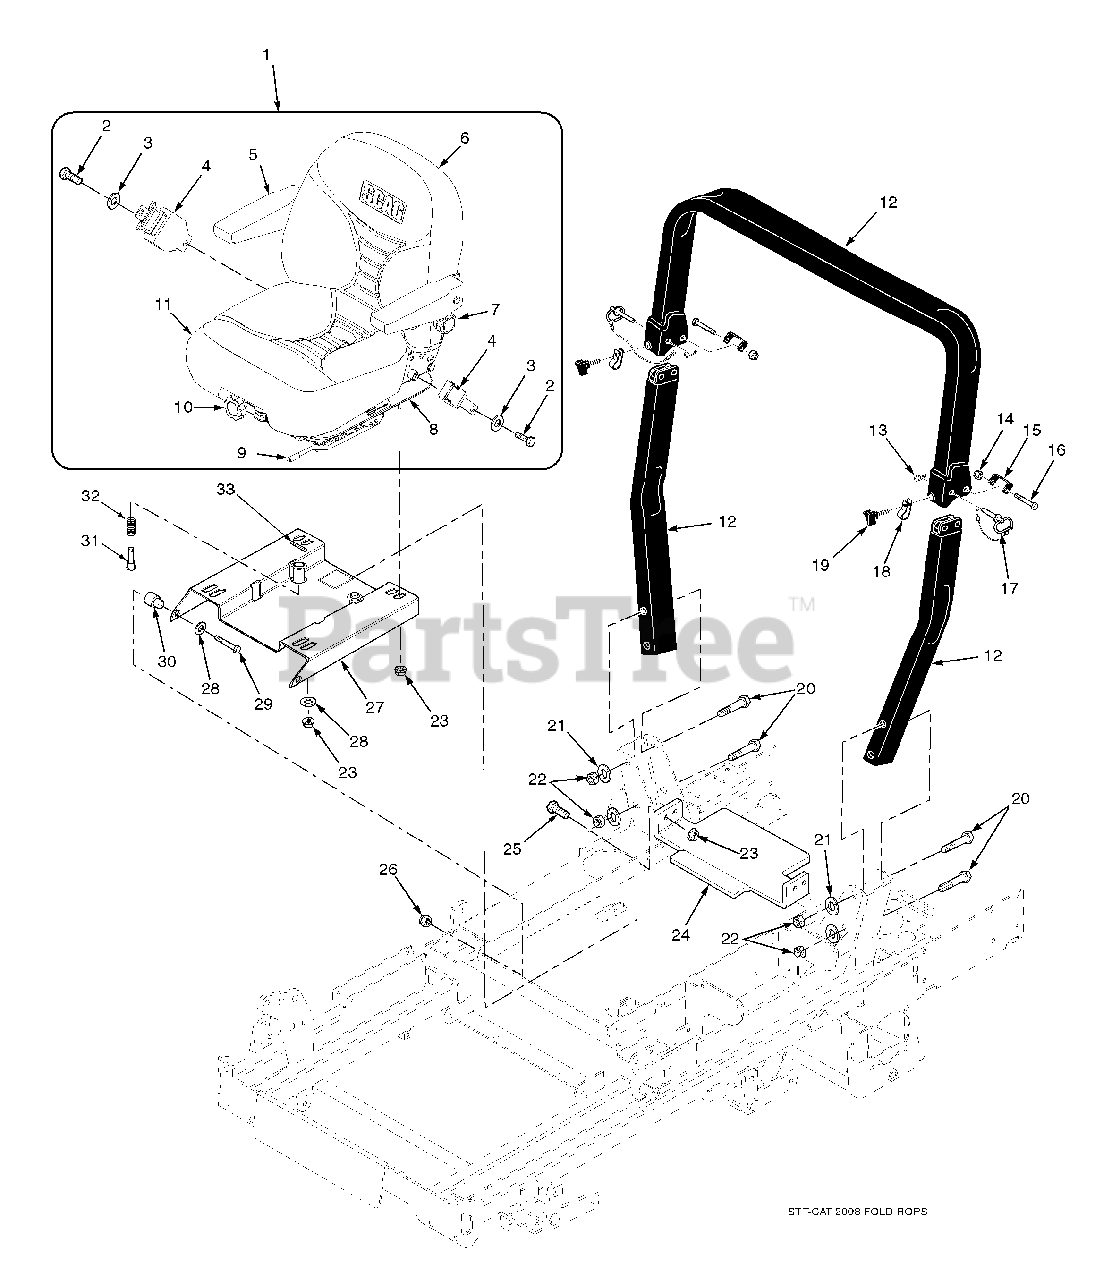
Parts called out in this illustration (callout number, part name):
1	Suspension Seat Assembly w/seat belt
2	Bolt, Hex Head 7/16-20 x 1”
3	Flatwasher, 7/16-.500 x 1.25 x .083
4	Retractable Seat Belt
5	Armrest Only
6	Back Cushion Kit
7	Lumbar Kit
8	Shock Absorber Kit
9	Seat Adjustment, Track Set
10	Weight Adjustment Kit
11	Seat Cushion Kit
12	STT, ROPS Accessory
13	Hair Pin, Cotter
14	Nut, Center Lock 1/2-13
15	Bracket, Stop
16	Bolt, Hex Head 1/2-13 x 3-1/2”
17	Pin
18	Clamp
19	Thumb Screw, 5/16-18 NC x 3/4”
20	Bolt, Hex Head 1/2-13 x 4-1/2”
21	Flatwasher, 1/2-.562 x 1.375 x .109
22	Nut, Center Lock 1/2-13
23	Nut, Serrated Flange 5/16-18
24	Bracket, Seat Hold Down with Decal
25	Bolt, Hex Head 5/16-18 x 1”
26	Nut, Elastic Stop 3/8-16
27	Seat Plate Weldment w/Decal
28	Flatwasher, 3/8-.391 x .938 x .105
29	Bolt, Hex Head 3/8-16 x 2”
30	Spacer Bushing
31	Pin Retainer, Spring
32	Spring, Seat
33	Roll Pin, Spring 5/32 x 3/4”
